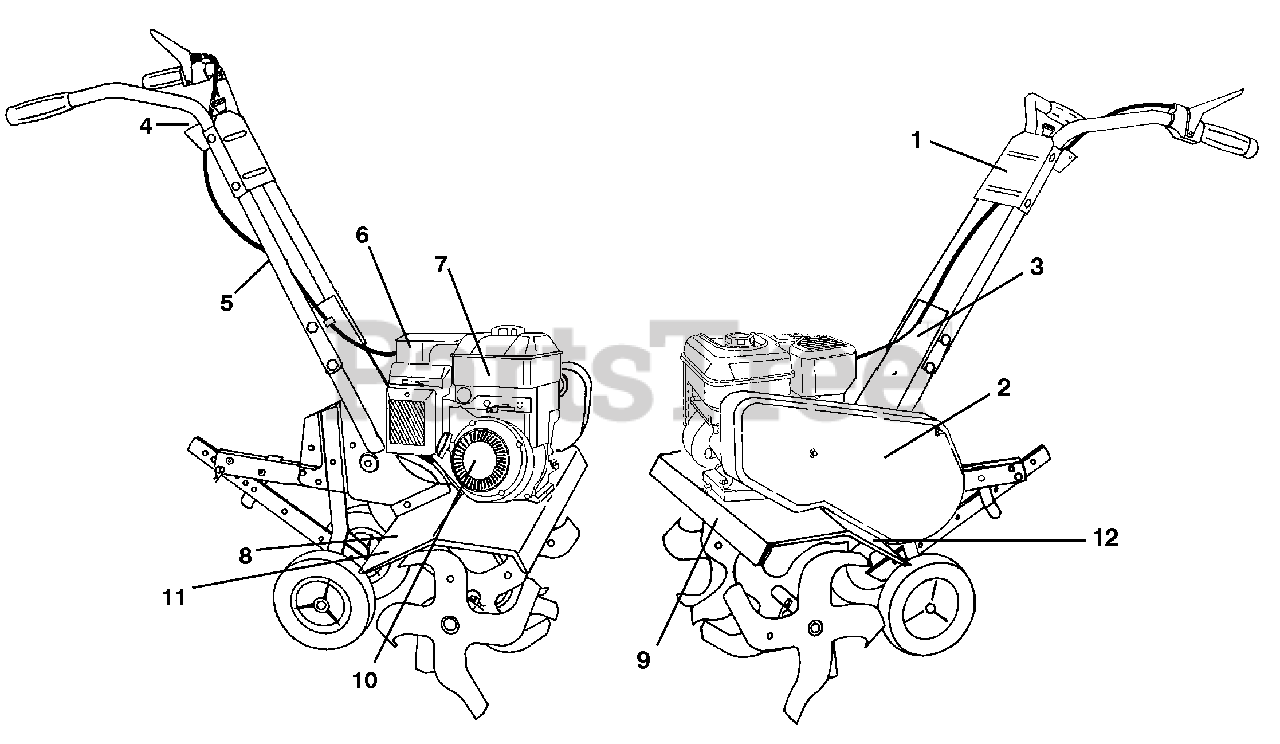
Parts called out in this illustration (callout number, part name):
1	Decal, Poulan Pro
2	Decal, Poulan Pro, 800 Series/26"
3	Decal, Forward and Reverse
4	Decal, Reverse, Tine Control
5	Decal, Hand Placement
6	Decal, Engine
7	Decal, OHV, I/C
8	Decal, Warning
9	Decal, Heavy Duty
10	Decal, Rewind Starter
11	Decal, Warning, Rotating Tines
12	Decal, Compliance
12	Manual, Operator's, English/French
12	Manual, Repair Parts
